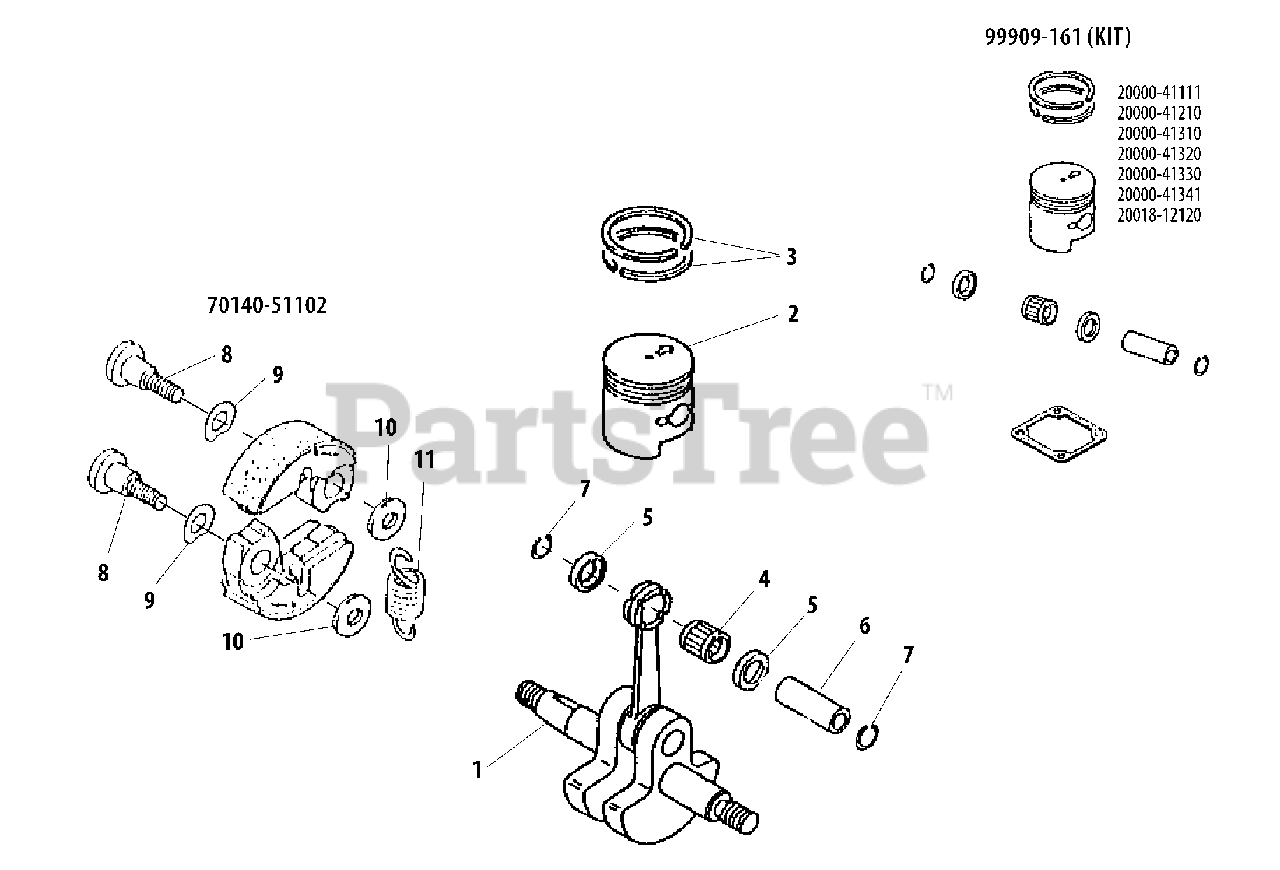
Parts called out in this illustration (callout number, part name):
1	CRANKSHAFT ASSY
2	PISTON
3	RING, PISTON
4	BEARING, NEEDLE
5	WASHER, THRUST - 9
6	PIN, PISTON
7	RING, RETAINING
8	BOLT, CLUTCH
9	WASHER - SPRING
10	WASHER - 6
11	SPRING, CLUTCH
A	PISTON KIT
A	CLUTCH ASSY
